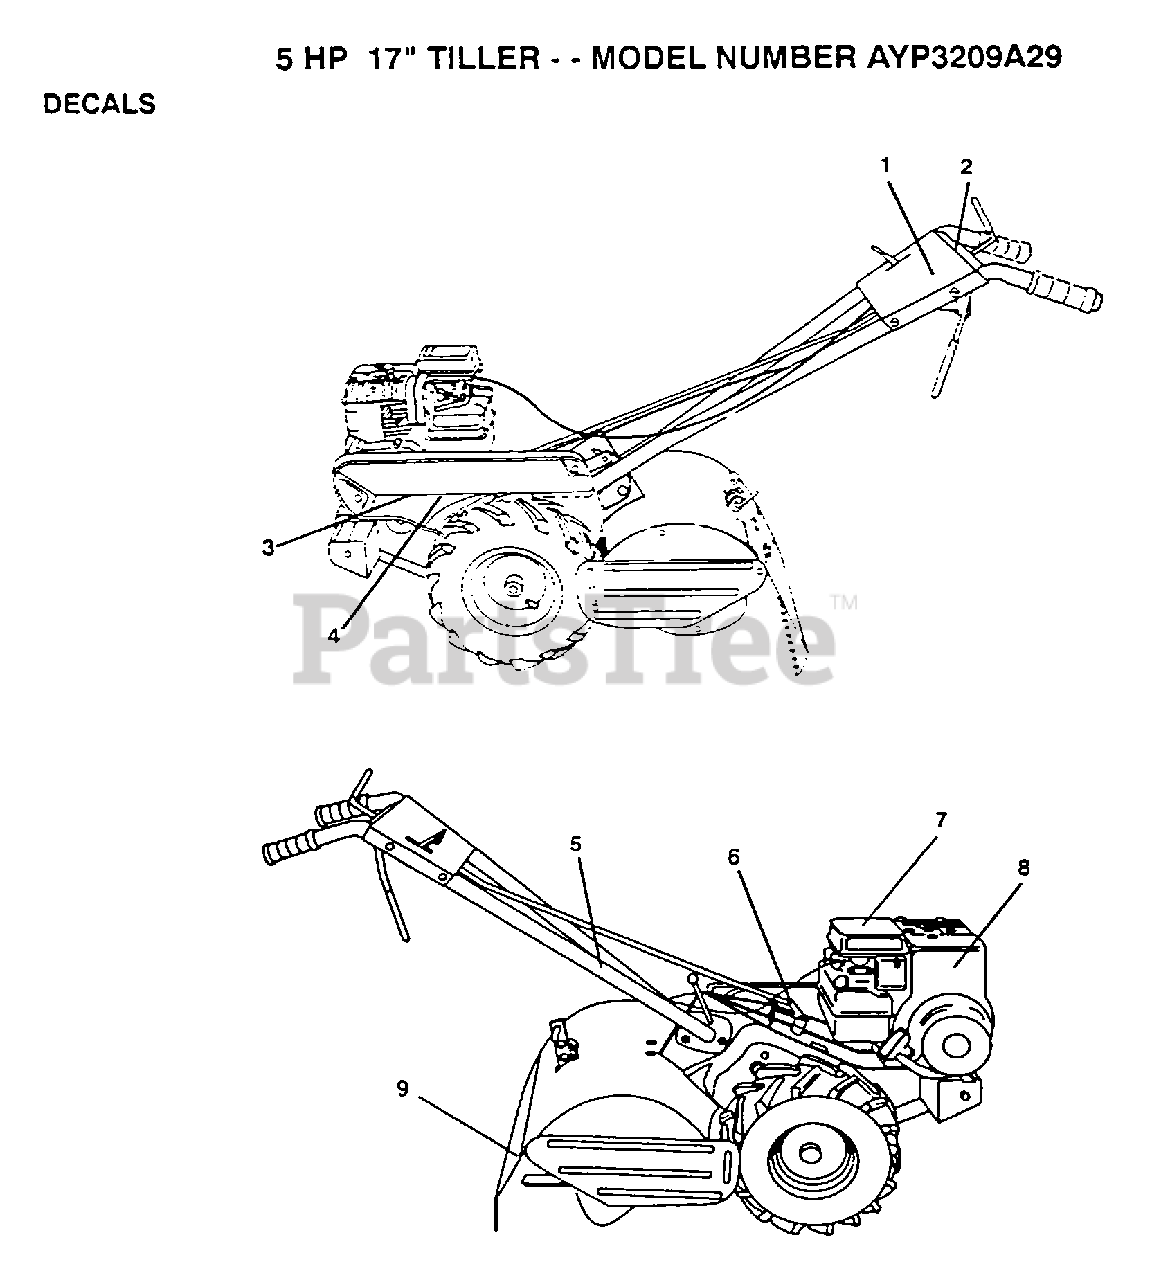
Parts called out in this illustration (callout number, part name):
1	DECAL LOGO WIZARD
5	DECAL TI
7	DECAL TI
